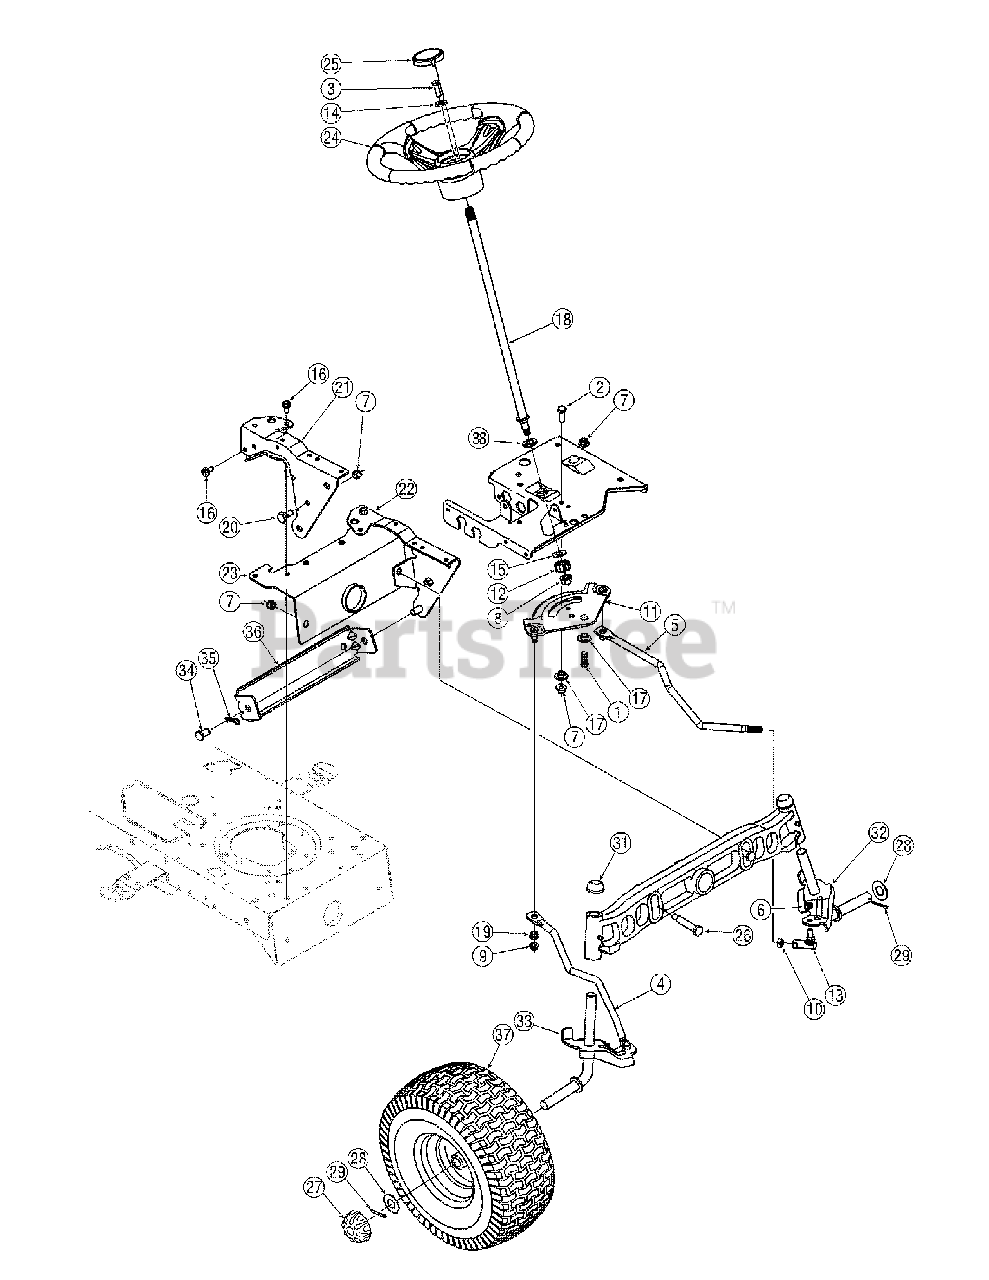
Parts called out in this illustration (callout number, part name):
1	Hex Screw, 3/8-16, 1.00, Gr5
2	Hex Screw, 3/8-16, 1.00, Gr5
3	Hex Screw, 5/16-18, 1.00, Gr5
4	Link, Drag, RH
5	Link, Drag, LH
6	Nut, Hex Lock, 3/8-24
7	Nut, Flange Lock, 3/8-16, Grf, Nylon
8	Nut, Flange Lock, 7/16-20
9	Nut, Flange Lock, 5/16-18, Gr5
10	Nut, Jam, 7/16-20, Gr2
11	Gear, Steering, 11/90 Ratio
12	Gear, Pinion, Steering
13	Ball Joint, 7/16-20, Lock
14	Washer, Flat, .406 x .875 x .105
15	Washer, Flat, .51 x 1.12 x .06
16	Screw, 5/16-12, 0.750
17	Spacer, Shoulder, .38 x 1.00 x .31
18	Shaft, Steering, .625 OD x 24.25 Lg
19	Plastic Bushing .380 ID
20	Screw, Shoulder, .498 x .340, 3/8-16
24	Steering Wheel, 13.25
25	Steering Wheel Cap, Round
26	Shoulder Screw, .5 x 2.2, 3/8-16
27	Deluxe Hub Cap
28	Flat Washer, .78 x 1.589 x .06
29	Cotter Pin, 5/32 x 1.25
30	Cast Iron Pivot Bar
31	Push Cap
32	LH Axle Assembly, .750
33	RH Axle Assembly, .750
34	Pin, Clevis, .50 x .78
35	Cotter Pin, Internal, .080 x 1.5625
38	Bearing, Hex Flange 5/8
